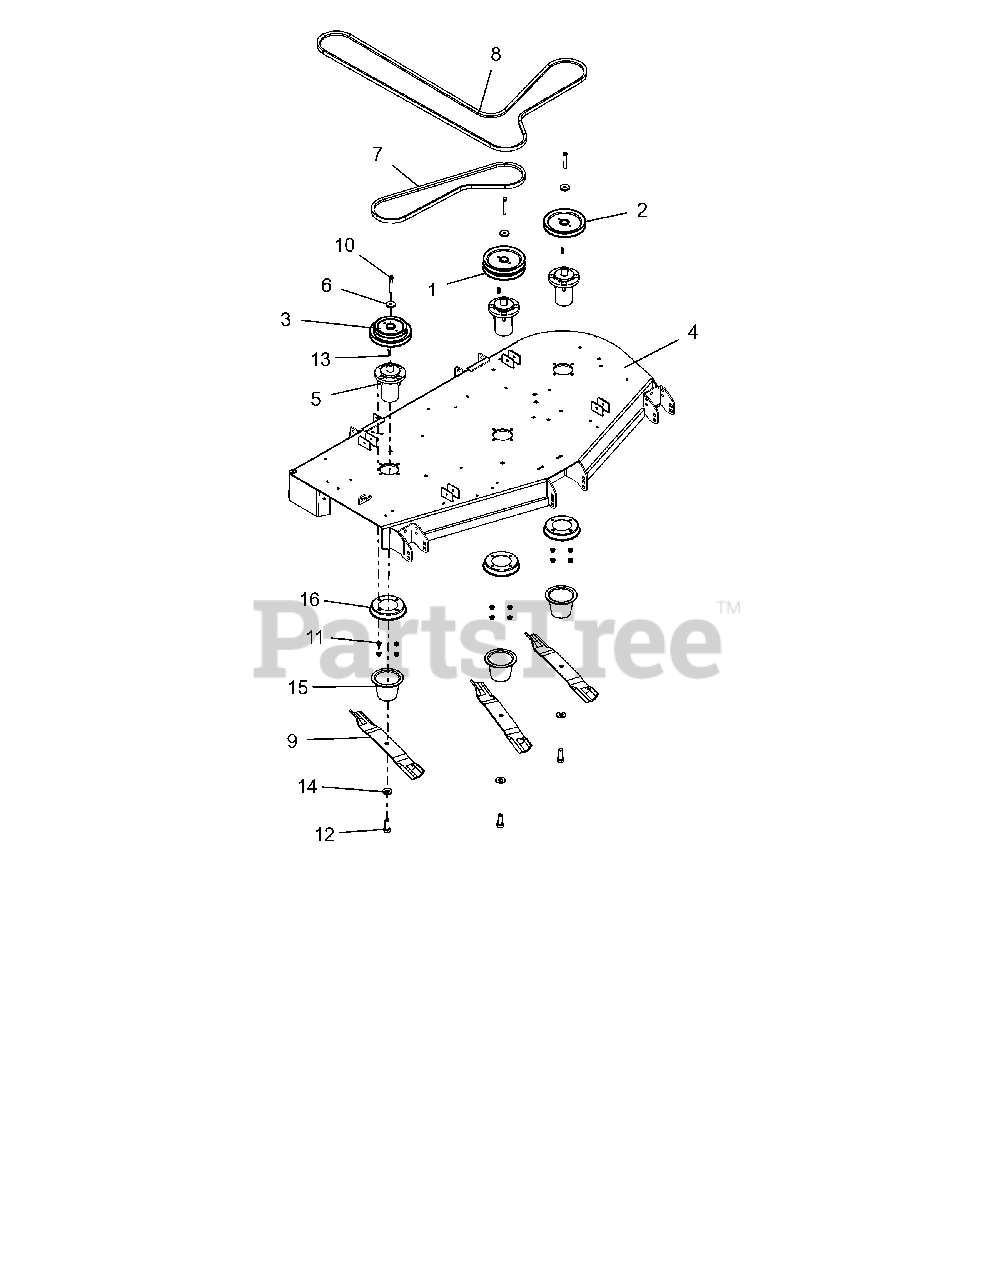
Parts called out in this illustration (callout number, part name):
1	PULLEY, DOUBLE-1"ID X 6.75"OD
2	PULLEY, V-1" ID X 6.75" OD
3	PULLEY, DBL-1"IDX6.75"&5.25"OD
4	60"SIDE DISCH DECK WMT W/SAFE
5	ASM, MAINT FREE ALUM SPINDLE
6	RETAINER, SHEAVE
7	V-BELT, B-COGGED
8	V-BELT, HB-WRAPPED
9	BLADE, MOWER (20.50")
10	BLT-HEX .38-16X2.75 GR8 YWZC
11	NUT-LK-CTR-FLG .38-16 YWZC
12	BLT-HEX .62-18X1.75 GR8 YWZC
13	KEY, SQ .25X.25X1.00 RC 40-50
14	WSHR-BLVL .669X1.535X.138
15	GUARD, SPINDLE LOWER
16	GUARD, SPINDLE TOP
